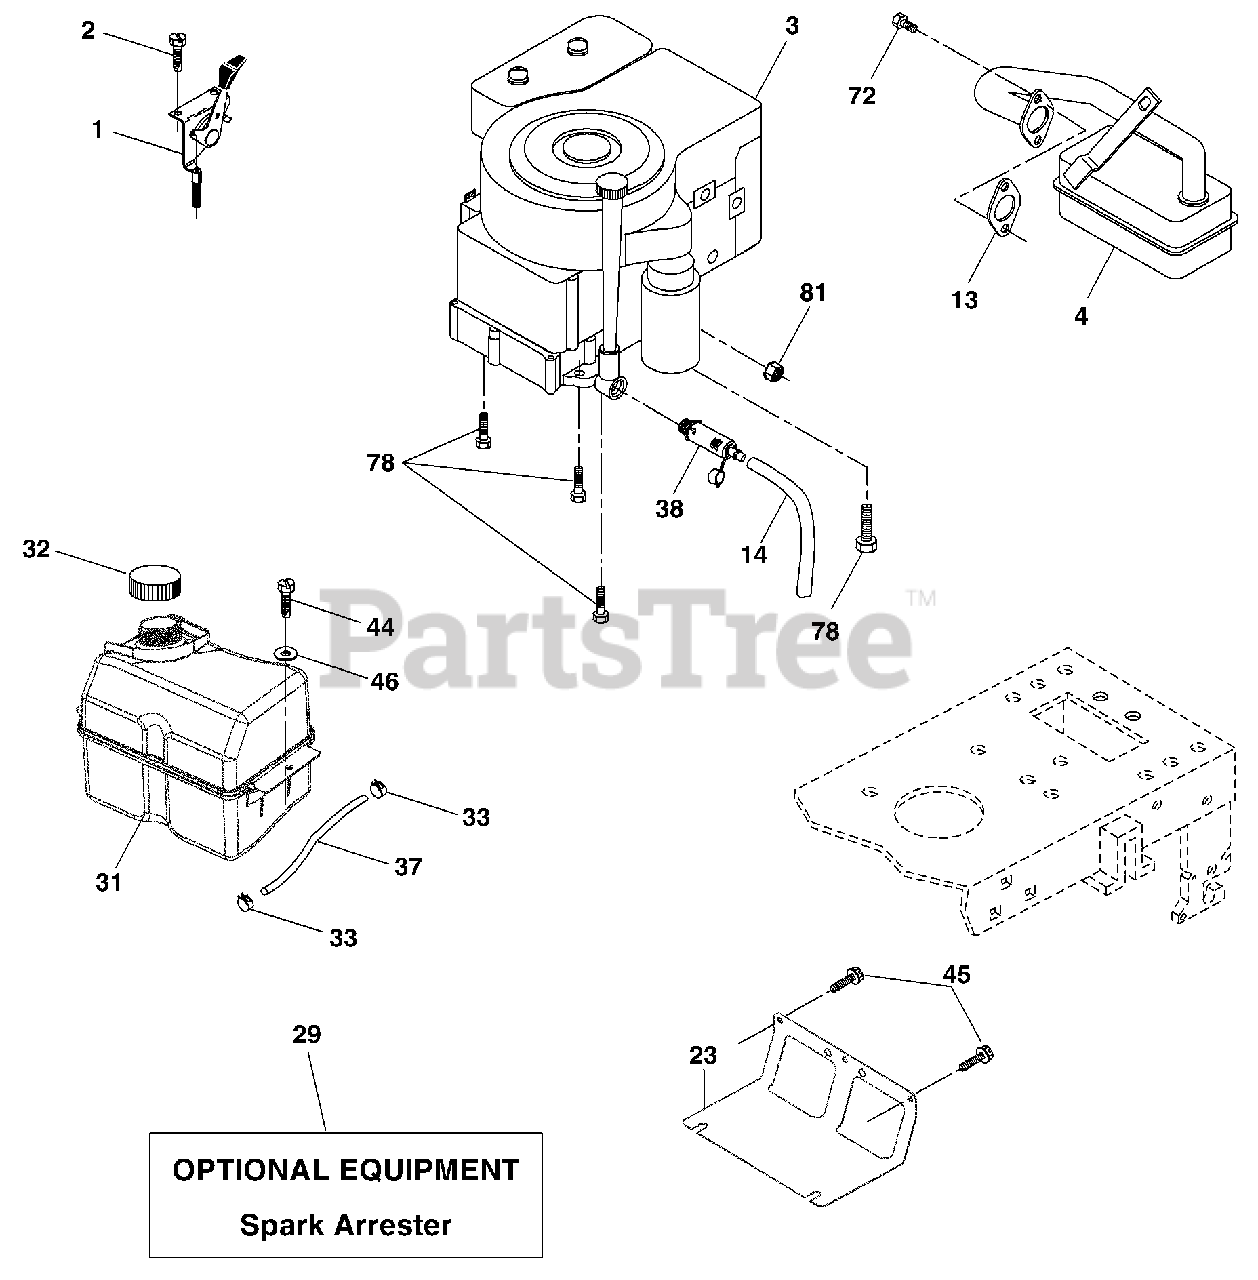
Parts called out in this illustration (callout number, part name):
1	Control Th/ch Flag
2	Screw Hex Thd Cut 1/4-20 x 1/2
4	Muffl er
13	Gasket Eng
14	Tube Drain Oil Easy
23	Shield Brn/Dbr Guard
29	Kit Spark Arrestor (Flat Scrn)
31	Tank Fuel Front
32	Cap Asm Fuel W/sym Vented
33	Clamp Hose Black
37	Line Fuel 20"
38	Plug Drain Oil Easy
44	Screw Hexwsh Thdrol 1/4-20 x 3/4
45	Screw Hexwsh Thdr 3/8-16 x 3/4
46	Washer 9/32 x 7/8 x 16 Ga
72	Screw Socket Head 5/16-18 x 1
78	Screw 3/8-16 x 1-1/4
81	Nut Keps Hex 1/4-20 unc
